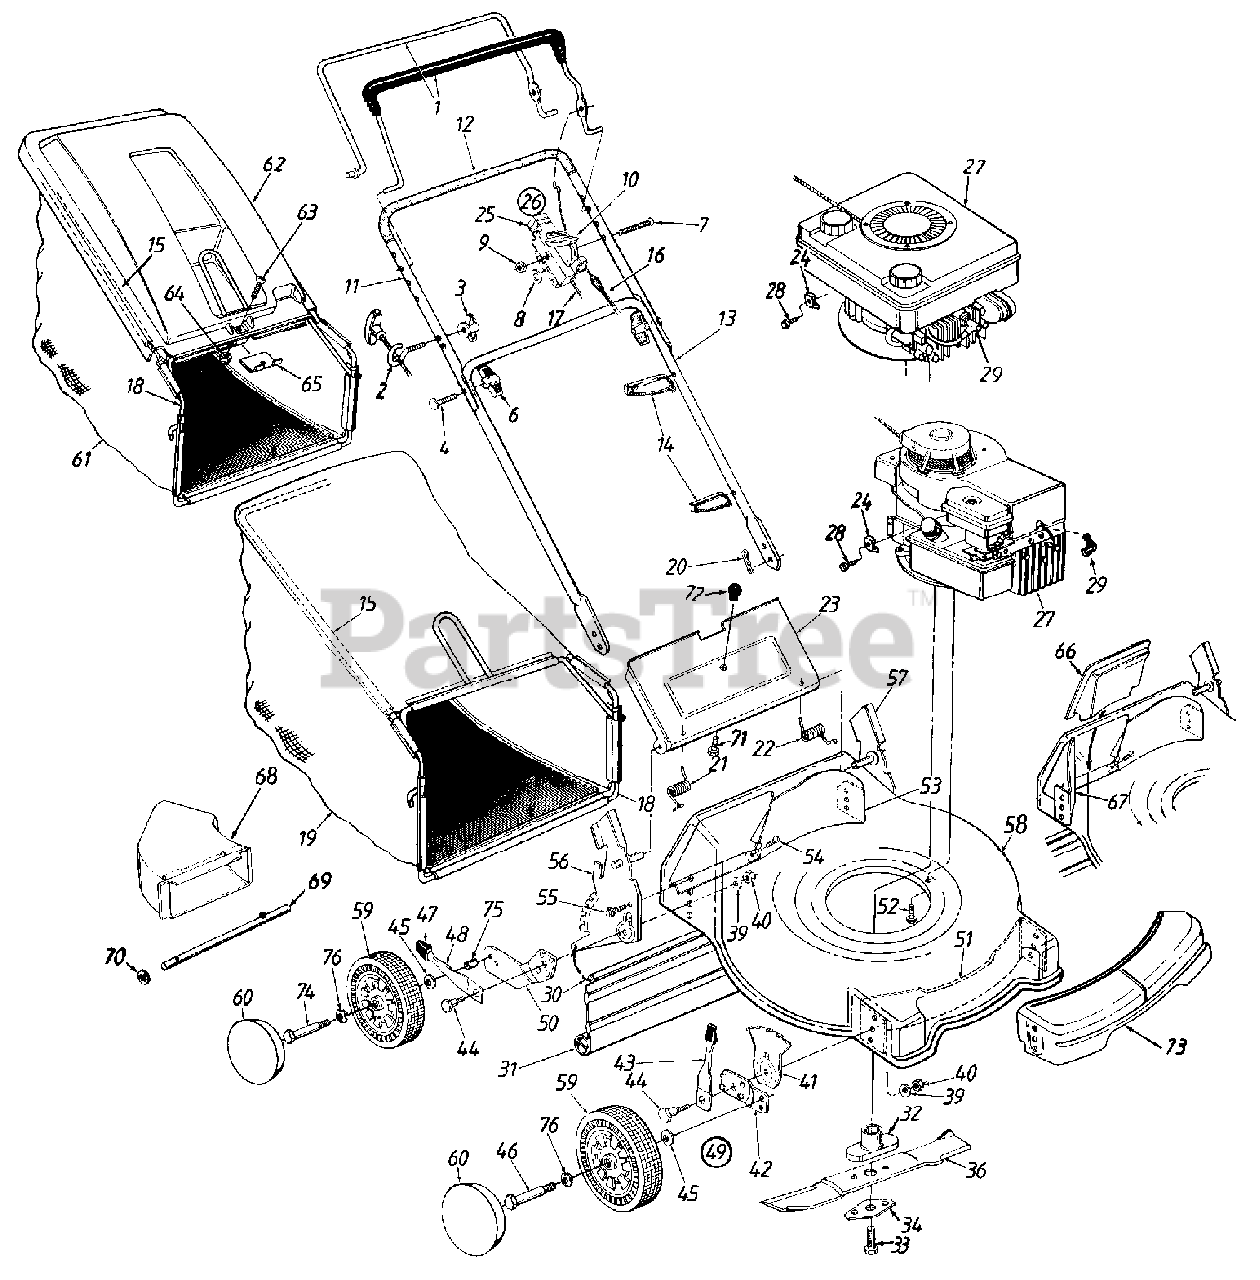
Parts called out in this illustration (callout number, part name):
2	Rope Guide
3	Handle Knob 1/4-20 Thd.
4	Curved Hd. Bolt 5/16-18 x 2" Lg
6	Hand Knob
7	Oval C-Sunk Mach. Scr.
8	Spr. Wash. .66" I.D.
9	Hex L-Nut 1/4-20 Thd.
10	Throttle Lever
14	Cable Tie
16	Control Cable-39"
17	Throttle Control Wire - 51"
20	Int. Cotter Pin 5/16" Dia.
21	Door Spring - R.H.
22	Door Spring - L.H.
25	Throttle Body
26	Throttle Box Comp.
27	Engine
28	Hex Wash. Hd. Scr. #10-32 x .62" Lg.
29	Spark Plug Boot
30	Wire Rod
31	Rear Flap
32	Blade Adapter Kit
33	Hex Bolt 3/8-24 x 1.5" Lg.
34	Blade Bell Support
36	21" Mulching Blade - 1 Bolt Mount
39	Bell-Wash. .39" I.D. x 1.38"
40	Hex Nut 3/8-16 Thd.
41	Height Adj. Plate
43	Spring Lever Ass'y. w/Knob
44	Shld. Bolt .5" Dia. x .357"
45	Bell-Wash. .38" I.D. x .88" O.D.
46	Axle Bolt
47	Spring Lever Knob
48	Spring Lever
49	Height Adj. Ass'y. Comp. - R.H.
50	Pivot Bar R.H.
54	Torx Mach. AB-Tap Scr. 1/4 x 62" Lg.
55	Hex Ind-Wash.Scr. 1/4-14 x .625 Lg.
59	Wheel Assy Comp. Wheel w/o Bearings Grey, Aero Bar Tread
59	Wheel Assy Comp. Wheel w/o Bearings Grey, Disc Hub Bar Tread
59	Wheel Assy Comp. Wheel with Bearings Grey Link Tread
60	Hub Cap - Gray, Rad. Spoke
61	Grass Bag
62	Hard Top Cover
63	Pan Hd. Mach. Scr. 1/4-20 x .5" Lg.
64	Hex Nylon L-Nut 1/4-20 Thd.
66	Mulching Baffle Plug
68	Deflector
69	Rod
70	Push Speed Nut
71	Truss Scr. #10-24 x .38" Lg.
73	Deck Shroud
74	Rear Axle Bolt
75	Spacer
76	Wave Washer
